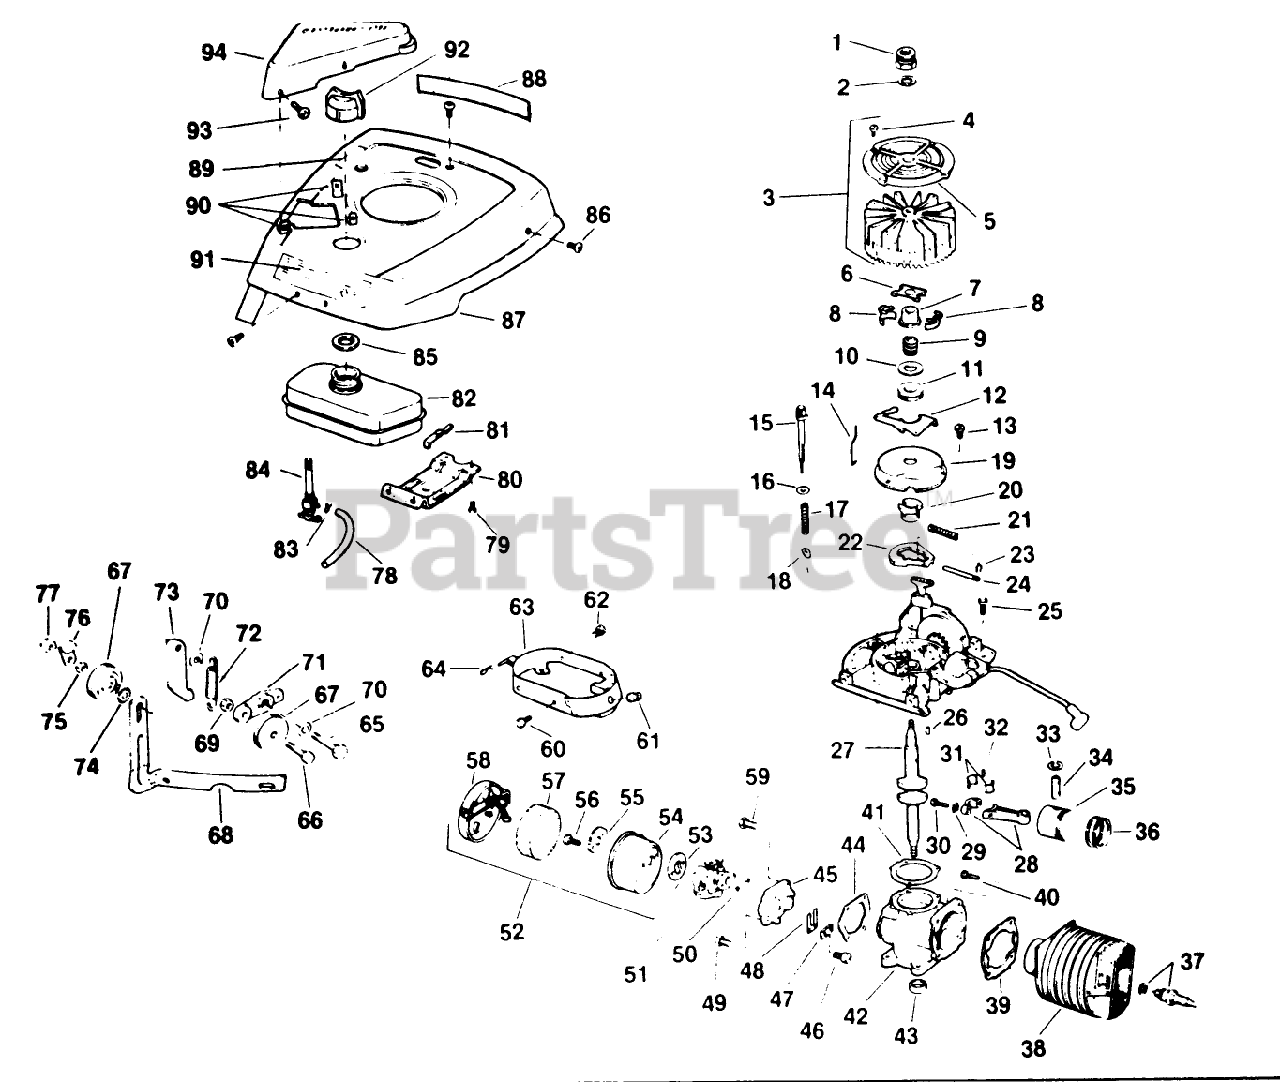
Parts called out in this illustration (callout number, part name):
3	Flywheel Screen Assy.
4	SCREW F
7	COLLAR S
11	THRUST COLLAR S
12	LEVER-GOVERNOR S
13	SCREW S
17	SPRING S
19	DUST COVER S
20	SPARK ADV. S
21	SPARK ADV. SPRING S
22	FLYWEIGHT S
23	SPARK ADJ. SPRING
24	PIN,SPARK ADV. S
31	LINER ASM
33	RING-RETAINING
37	Spark Plug and Gasket
39	GASKET S
41	GASKET S
44	GASKET S
45	REED PLATE AY. S
47	PLATE-BACKUP, REED
49	SCREW S
50	GASKET S
53	GASKET S
56	SCREW S
57	AIR FIL.ELEM S
59	SCREW S
60	SCREW S
61	NUT-CLIP
67	IDLER PULLEY
78	GAS LINE
79	SCREW S
83	CLAMP - HOSE S
84	VALVE&SCREEN SM
86	SCREW S
91	Decal-Instructions
94	BELT COVER AY
